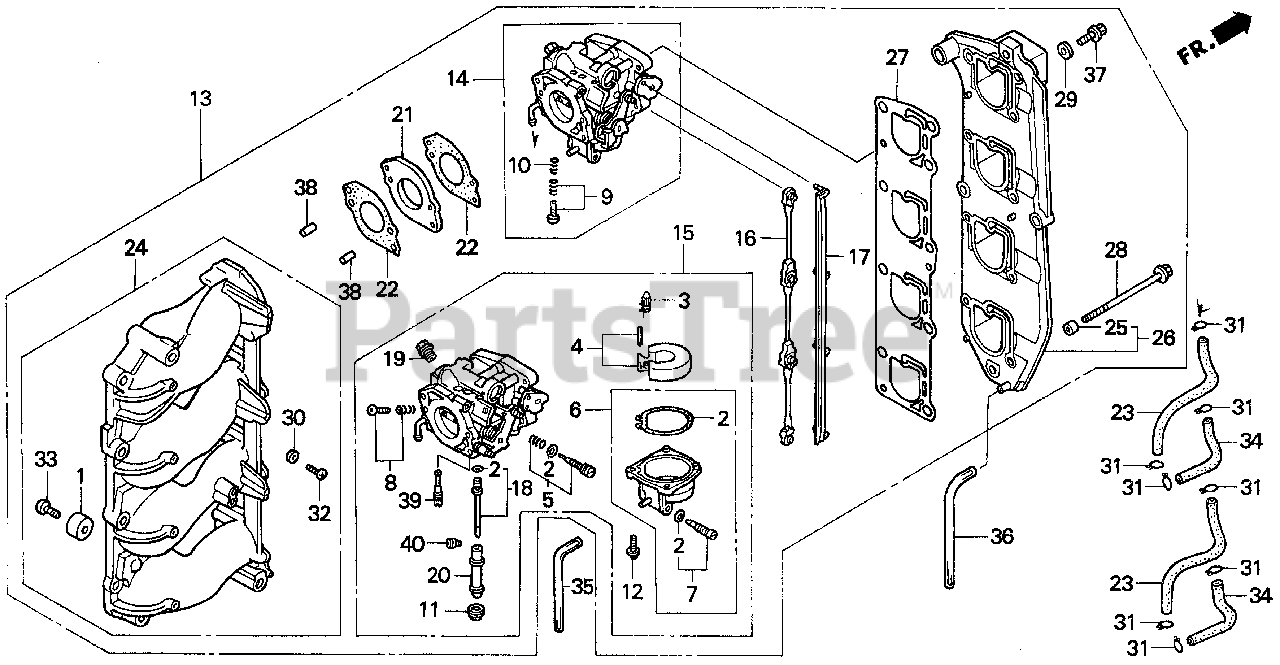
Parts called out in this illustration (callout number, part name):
1	METAL, ANODE
2	GASKET SET
3	VALVE SET, FLOAT
4	FLOAT SET
6	CHAMBER SET, FLOAT
7	SCREW SET, DRAIN
11	SCREW, PLUG
12	SCREW-WASHER
13	CARBURETOR ASSY. (BG40B B) *NH8* (DARK GRAY)
14	CARBURETOR ASSY. (#1 #2 #3)
15	CARBURETOR ASSY. (#4)
15	CARBURETOR ASSY.
16	LEVER, LINK
17	LINK, CHOKE
18	JET SET (#40)
19	BOLT, HOLDING
20	NOZZLE, MAIN
21	INSULATOR, CARBURETOR
22	GASKET, CARBURETOR
23	TUBE A, FUEL
24	MANIFOLD ASSY., IN. *NH8* (DARK GRAY)
25	COLLAR, DISTANCE (6.5X11X7.5)
26	PLATE, MUFFLER
26	CARBURETOR ASSY. (BG35F C) *NH8* (DARK GRAY)
27	GASKET, MUFFLER PLATE
28	BOLT, FLANGE (6X106)
29	WASHER (6MM)
30	WASHER, SEALING (5MM)
31	CLIP, TUBE (B10)
32	SCREW, PAN (5X10)
33	SCREW, PAN (6X18)
34	BULK HOSE, FUEL (5.5X3000) (5.5X175)
35	BULK HOSE, VINYL (3.5X6.5X8000) (3.5X6.5X230)
36	BULK HOSE, VINYL (3.5X6.5X8000) (3.5X6.5X290)
37	BOLT, FLANGE (6X20)
38	ROLLER (6X15)
39	JET, SLOW (#52)
40	JET (#128)
40	JET, MAIN (#128)
40	JET, MAIN (#130)
40	JET, MAIN (#132)
